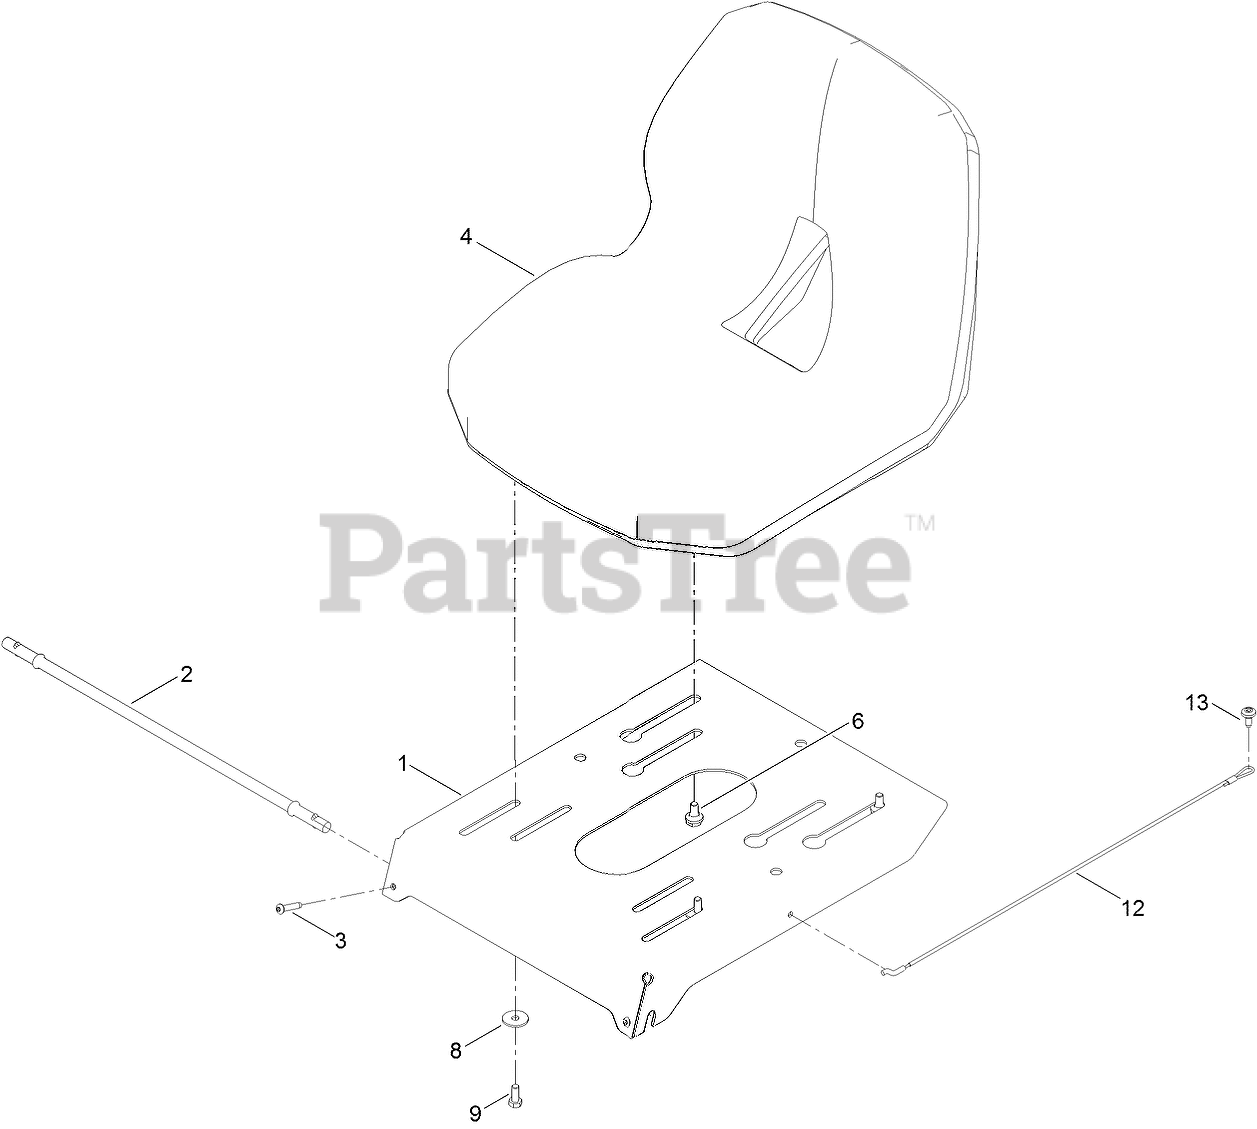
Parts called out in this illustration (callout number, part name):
1	PAN-SEAT
2	ROD-PIVOT
3	SCREW-BHCS
4	SEAT-16 IN
6	BOLT-SHOULDER,HFH
8	WASHER-PIVOT
9	SCREW-HH
12	CABLE-LANYARD
13	SCREW-SHOULDER
